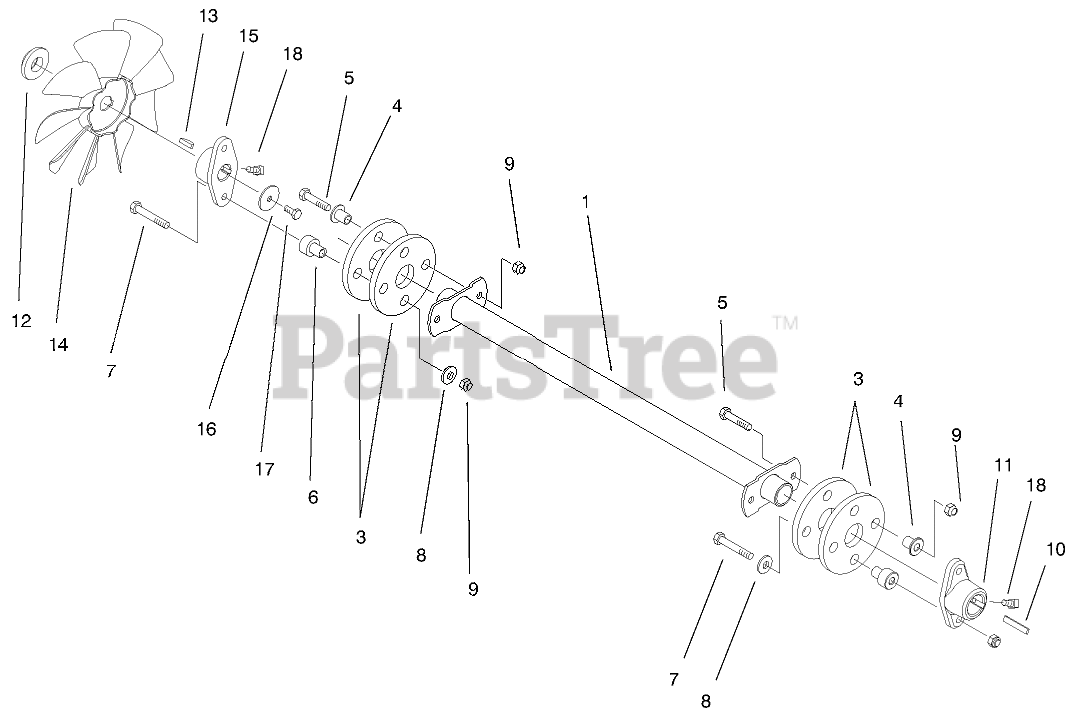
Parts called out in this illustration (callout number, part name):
1	SHAFT-DRIVE
3	COUPLING-RUBBER
4	SPACER
5	SCREW-HH
6	SPACER
7	SCREW-HH
8	WASHER-FLAT
9	NUT-LOCK, NI
10	KEY-SQUARE
12	SPACER-FAN
13	KEY-WOODRUFF
14	FAN-HYDRO
16	WASHER
17	SCREW-HH
18	SCREW-SET
